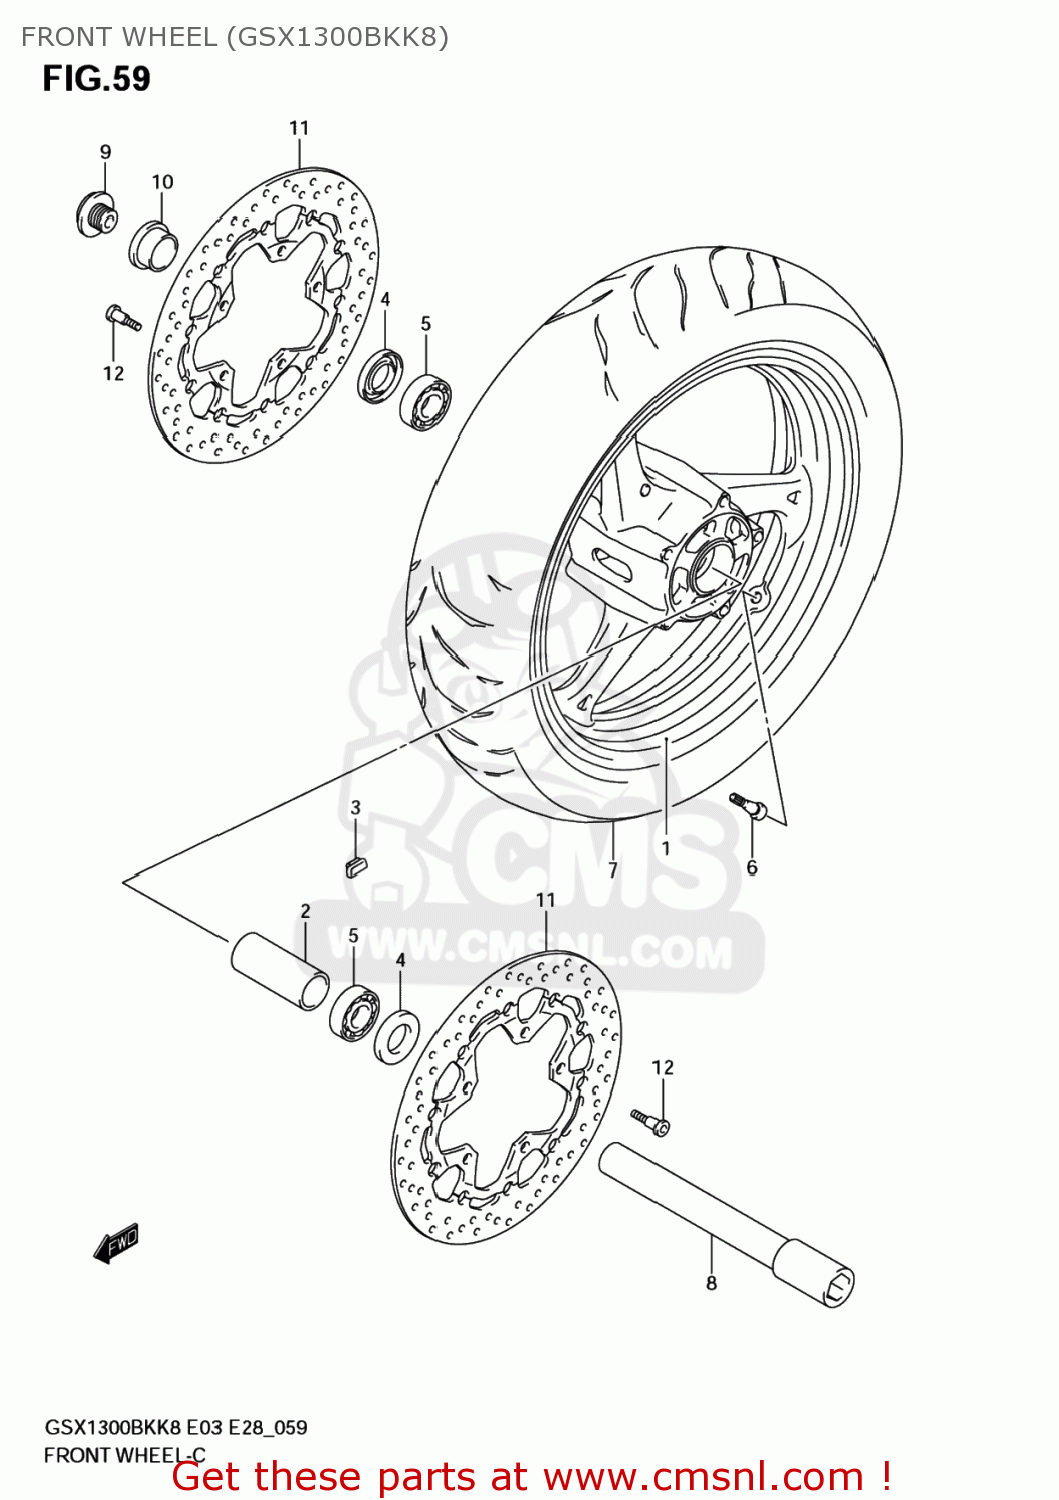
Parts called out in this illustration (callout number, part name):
1	WHEEL,FR(17M/CXMT3.50)
2	SPACER,FR HUB BEARING
3	BALANCER,WHEEL(10G)
4	SEAL,OIL(32X52X7)
5	BEARING(25X52X15)
6	VALVE ASSY,WHEEL RIM(TR412)
7	TIRE,FR
8	AXLE,FR
9	BOLT,FRONT AXL
10	SPACER,FRONT A
11	DISC,FRONT BRA
12	BOLT(8X21)
